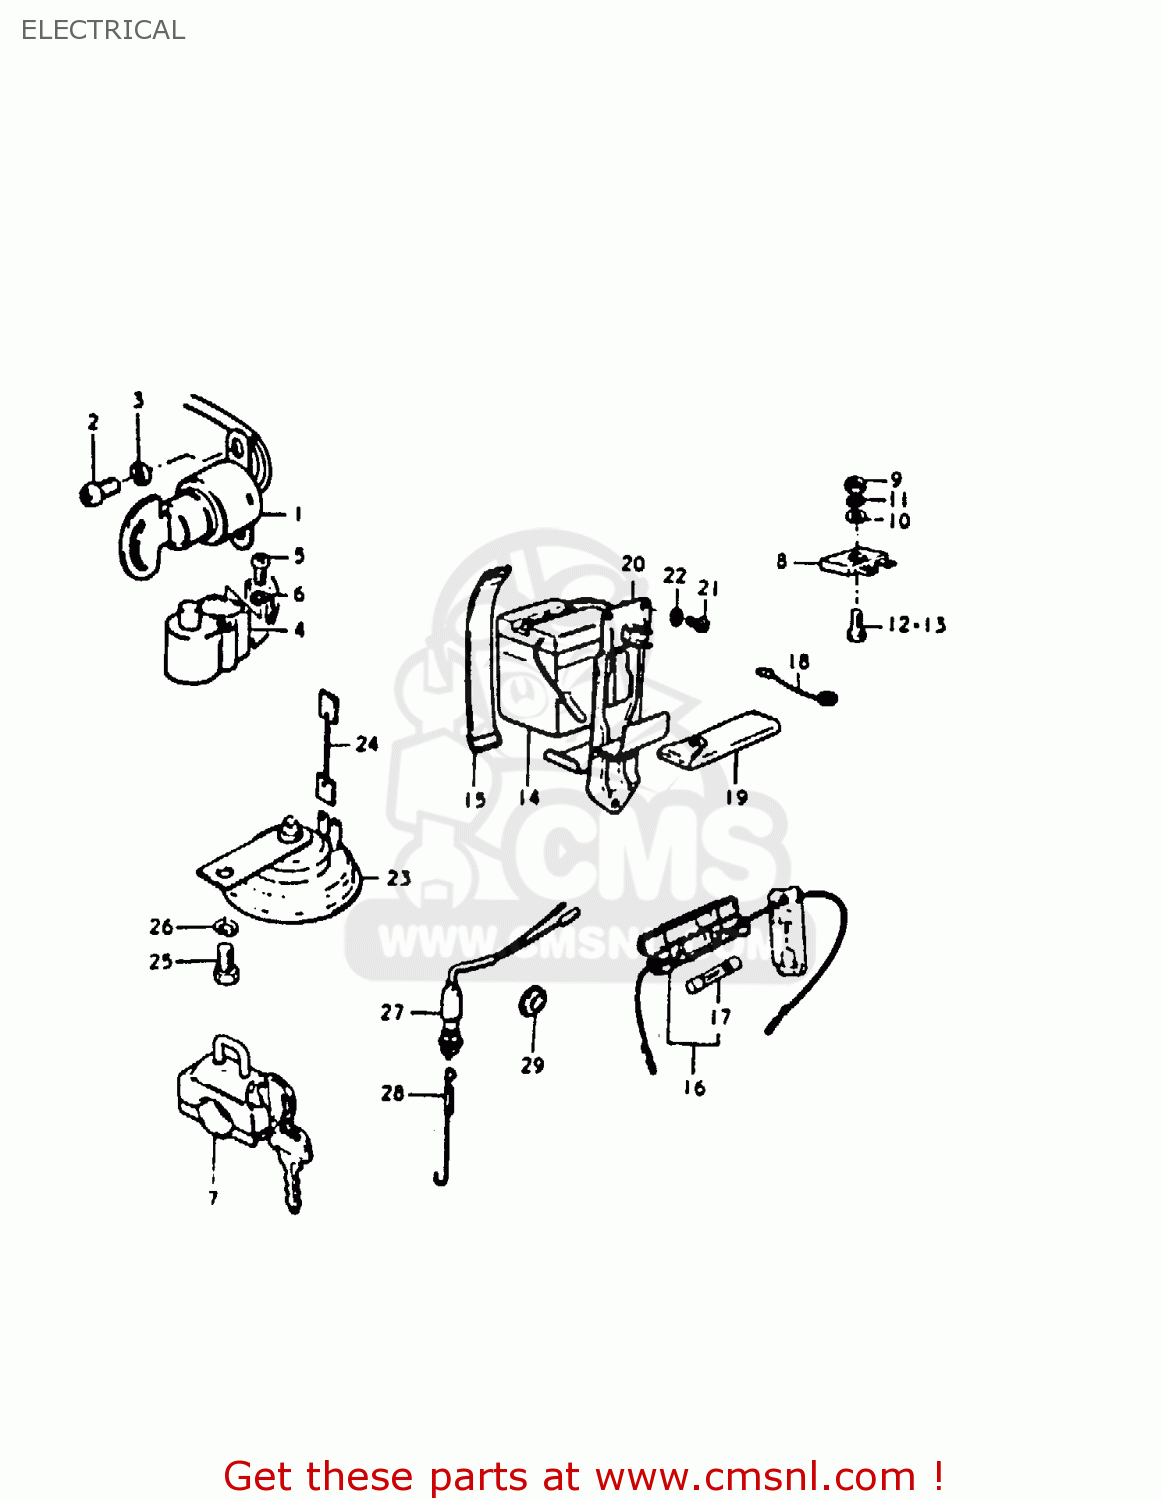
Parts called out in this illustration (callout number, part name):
1	SWITCH ASSEMBLY,IGNITION
2	SCREW 6X12
3	LOCK WASHER
4	LOCK ASSEMBLY,STEERING
5	SCREW
6	LOCK WASHER
7	LOCK ASSY, HELMET
8	RECTIFIER ASSEMBLY
9	NUT
10	WASHER
11	LOCK WASHER
12	BOLT 5X20
14	BATTERY ASSY(6N4-2A4.2AH)
15	BAND
16	BOX ASSEMBLY,FUSE
17	FUSE(15A)
18	LEAD WIRE
19	TOOL SET
20	HOLDER,BATTERY
21	SCREW(6X10)
22	LOCK WASHER
23	HORN ASSEMBLY
24	LEAD WIRE
25	BOLT 8X12
26	LOCK WASHER
27	SWITCH ASSY, STOP LAMP
28	SPRING
29	GROMMET
